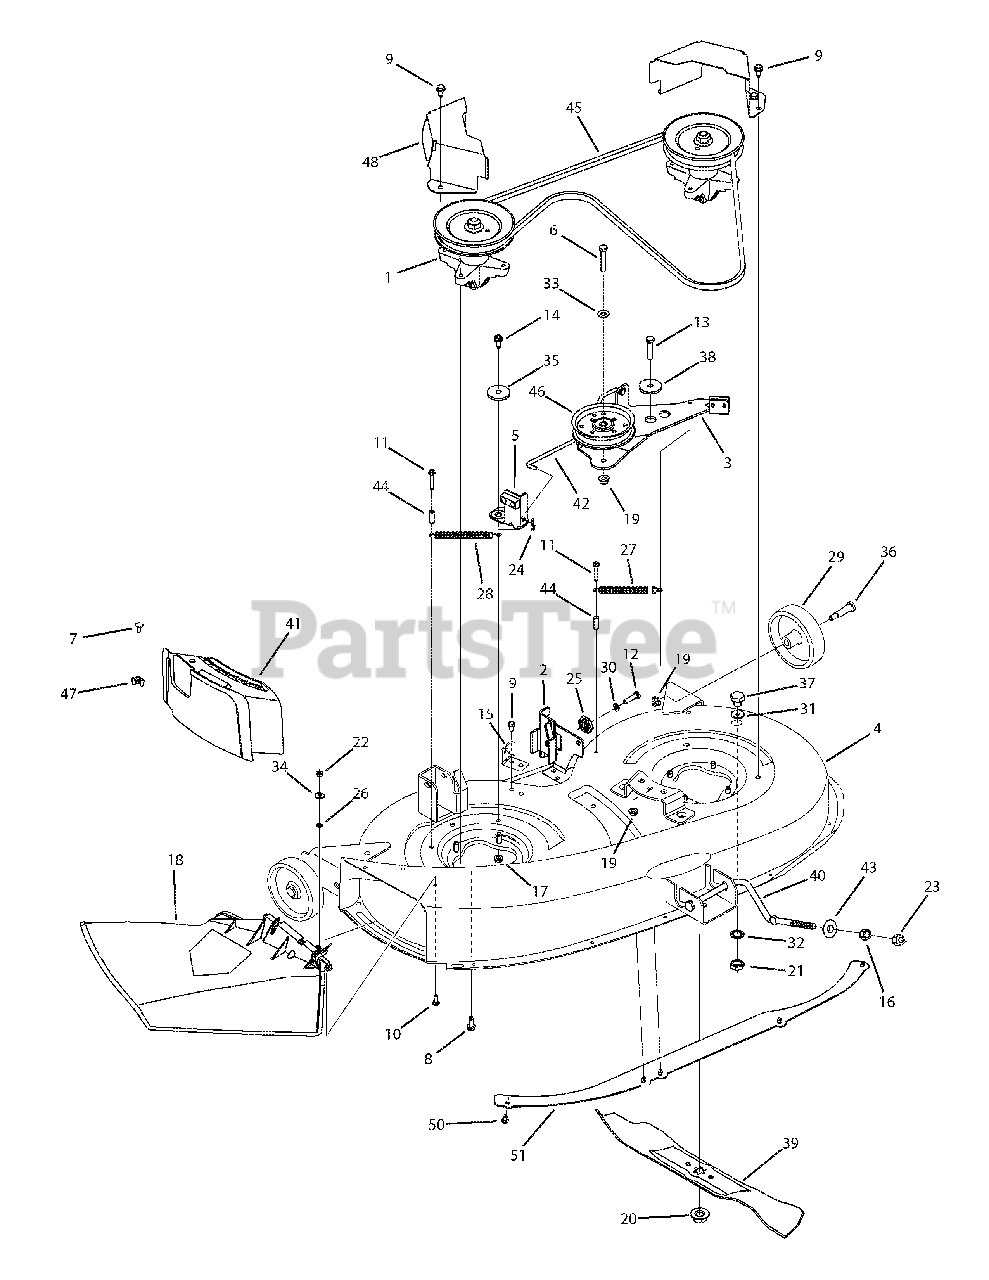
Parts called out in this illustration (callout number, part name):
1	Pulley Spindle Ass’y 5.75 dia.
4	Deck Shell, 38"
6	Hex Screw 3/8-16 x 1.75
7	Carriage Bolt 1/4-20 x .62
8	S-Tapp Scr 5/16-18 x .75
9	Hex Scr 5/16-18 x .625
10	Hex Bolt 1/4-20 x 1.00
11	Hex Wash HD Bolt 1/4-20 x 1.50" Lg.
12	Hex Wash Tap Scr 5/16-18 x 1.25
13	Hex Bolt 3/8-16 x 1.25
14	Hex Bolt 5/16-18 x .75" Lg. Gr. 5
16	Hex Nut 1/2-13
17	Hex Flange Locknut 5/16-18 Gr. F, Nylon
18	Side Discharge Chute Assembly
19	Hex Flange Locknut 3/8-16 Gr. F Nylon
20	Hex Flange Locknut 5/8-18
21	Hex Nut M16-1.5 DIN 936
22	Hex Nut 1/4-20 Gr. 5
23	Hex Nut, 1/2-13
24	Int. Cotter Pin .072 x 1.13" Lg.
25	Deck Adjustment Gear
26	Bolt Retainer 1/4" x .50" OD
27	Extension Spring .75 dia. x 6.37 Lg.
28	Extension Spring .50 dia x 6.37
29	Wheel Ass’y - Deck 5" x 1.38"
30	L-Wash 5/16 ID
31	Flat Washer .640 ID x 1.24 OD x .06
32	L-Washer Internal
34	Cupped Washer .265 ID x .75 OD x .062
35	Shoulder Spacer
36	Shoulder Bolt .498 Dia x 1.53 x 3/8-16
37	Screw Plug M16 x 1.50
38	Shoulder Spacer .8540 x .200
39	3 in 1 Blade 19.38" Lg.
40	Deck Rod, Front Adjustable
41	Mulching Plug
42	Brake Control Rod
43	Deck Lift Pivot Cup
44	Spacer .260 x .375 x 1.030 Lg.
45	V-Belt
46	Idler Poulie w/Flange 4.25 Dia
47	Wing Nut 1/4-20 Thd.
50	Screw, 1/4-20 x .50
